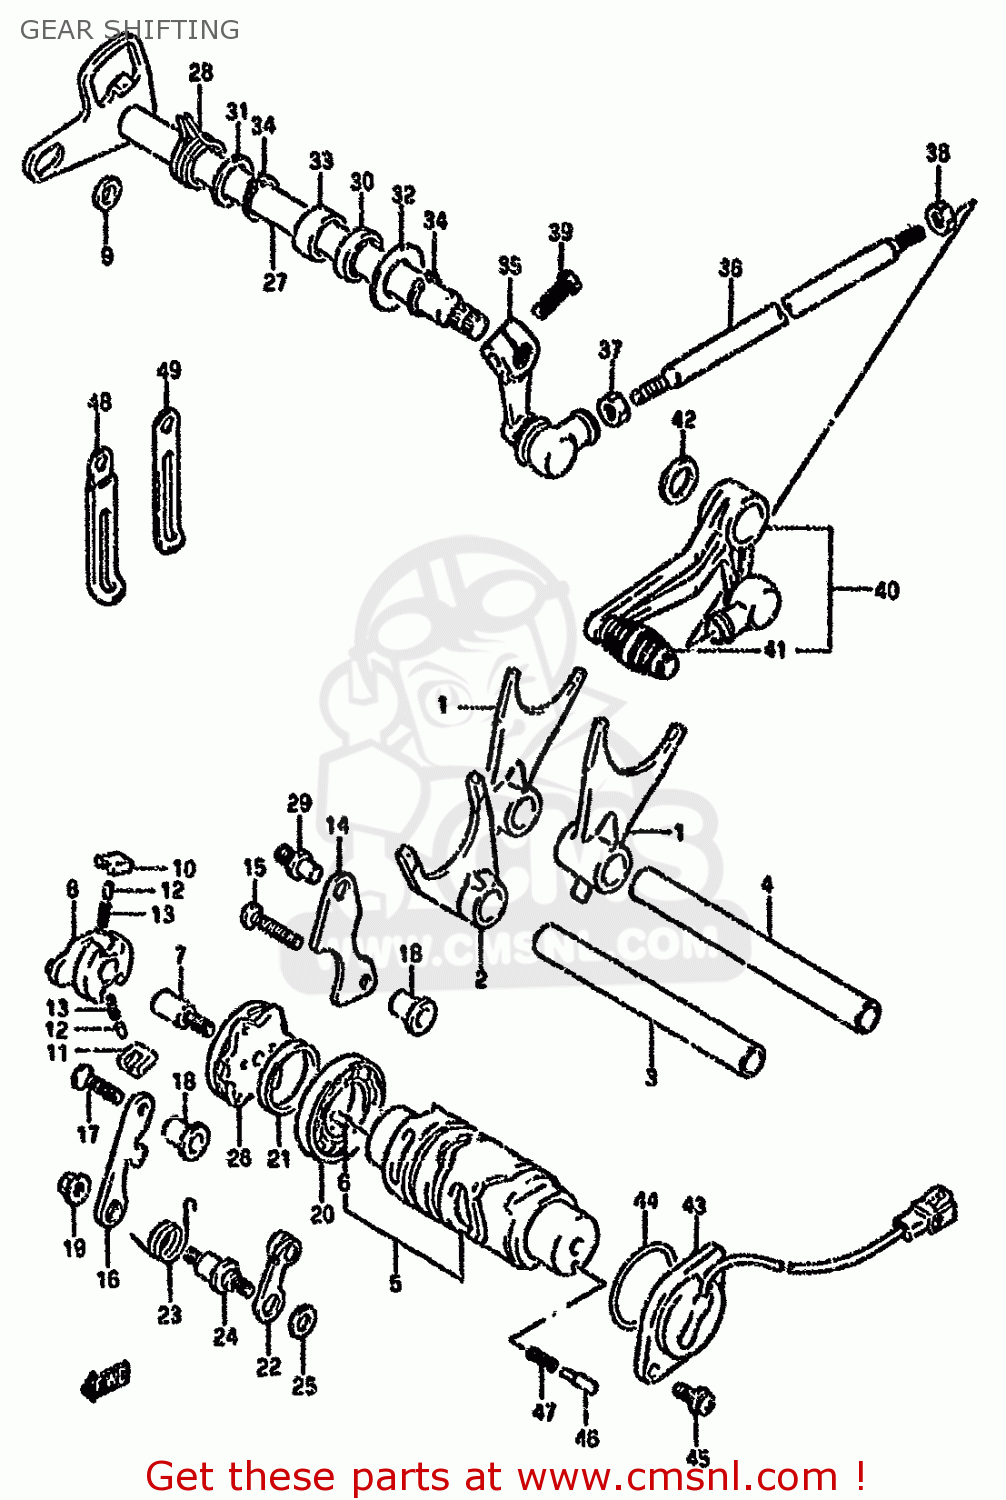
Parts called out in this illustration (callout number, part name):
1	FORK,GEAR SHIFT NO.1
2	FORK,GEAR SHIFT NO.3
3	SHAFT,GEAR SHIFT FORK
4	SHAFT,GEAR SHIFT FORK(L:128)
5	CAM,GEAR SHIFT
6	PIN
7	PIN,SHIFT CAM DRIVEN GEAR
8	SHIFTER,GEAR SHIFT CAM
9	SPACER(7X10X5)
10	PAWL,GEAR SHIFT NO.1
11	PAWL,GEAR SHIFT NO.2
12	PIN(5X8)
13	SPRING
14	LIFTER,GEAR SHIFT PAWL
15	SCREW 6X30
16	GUIDE,GEAR SHIFT CAM
17	SCREW
18	SPACER(6.1X10X16)
19	NUT
20	BEARING
21	WASHER(25X32X3)
22	STOPPER,GEAR SHIFT CAM
23	SPRING,STOPPER ARM
24	SUPPORT,CAM STOPPER ARM
25	WASHER
26	PLATE,GEAR SHIFT CAM
27	SHAFT,GEAR SHIFT
28	SPRING
29	STOPPER,GEAR SHIFT CAM
30	SEAL,OIL(14X22X6)
31	WASHER,THRUST
32	WASHER
33	BEARING(14X20X12)
34	CIRCLIP
35	ARM,GEAR SHIFT LINK
36	ROD,GEAR SHIFT LINK
37	NUT
38	NUT
39	BOLT
40	LEVER ASSEMBLY,GEAR SHIFTING
41	RUBBER,GEAR SHIFT PEDAL
42	WASHER(18X24X1)
43	TERMINAL BASE ASSY,NEUTRAL
44	O RING(D:2.4,ID:36.5)
45	SCREW
46	PIN(5X15.5)
47	SPRING
48	CLAMP
49	CLAMP
